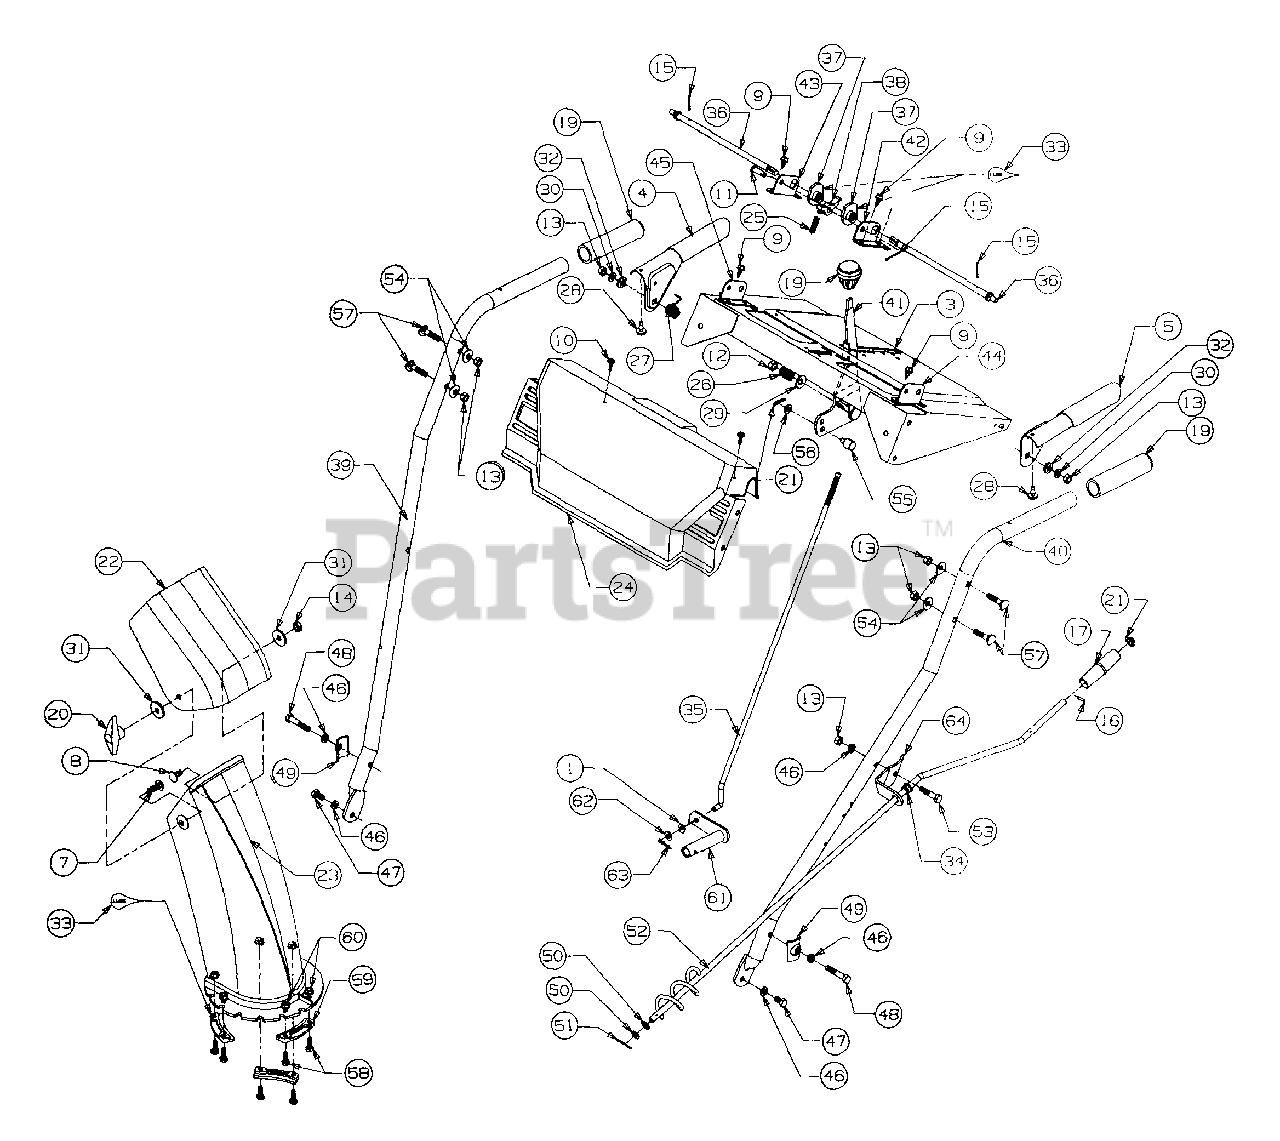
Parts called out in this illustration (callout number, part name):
5	Handle-Engagement - L.H.
7	Screw
8	Bolt-Carriage
9	Screw
10	Screw
11	Pin-Clevis
12	Nut-Hex
13	Nut-Hex
14	Nut-Lock
15	Pin-Cotter
16	Pin-Roll
21	Cap-Push
22	Chute-Upper
23	Chute-Lower
24	Panel Handle
25	Spring
26	Spring
27	Spring
28	Bumper
29	Washer-Bell
30	Washer-Lock
31	Washer
32	Washer
33	Lubricant
34	Bushing-Plastic
35	Rod-Shift
36	Rod-Cam
37	Cam-Handle Lock
38	Pawl-Handle Lock
46	Washer-Lock
47	Screw
48	Screw
49	Tab-Handle
50	Washer-Flat
51	Pin-Cotter
52	Crank-Chute
53	Screw
54	Washer-Bell
55	Ferrule
56	Washer-Flat
57	Bolt-Carriage
58	Screw
59	Keeper-Chute Flange
60	Nut-Lock
61	Washer-Spring
62	Washer-Flat
63	Pin-Cotter
